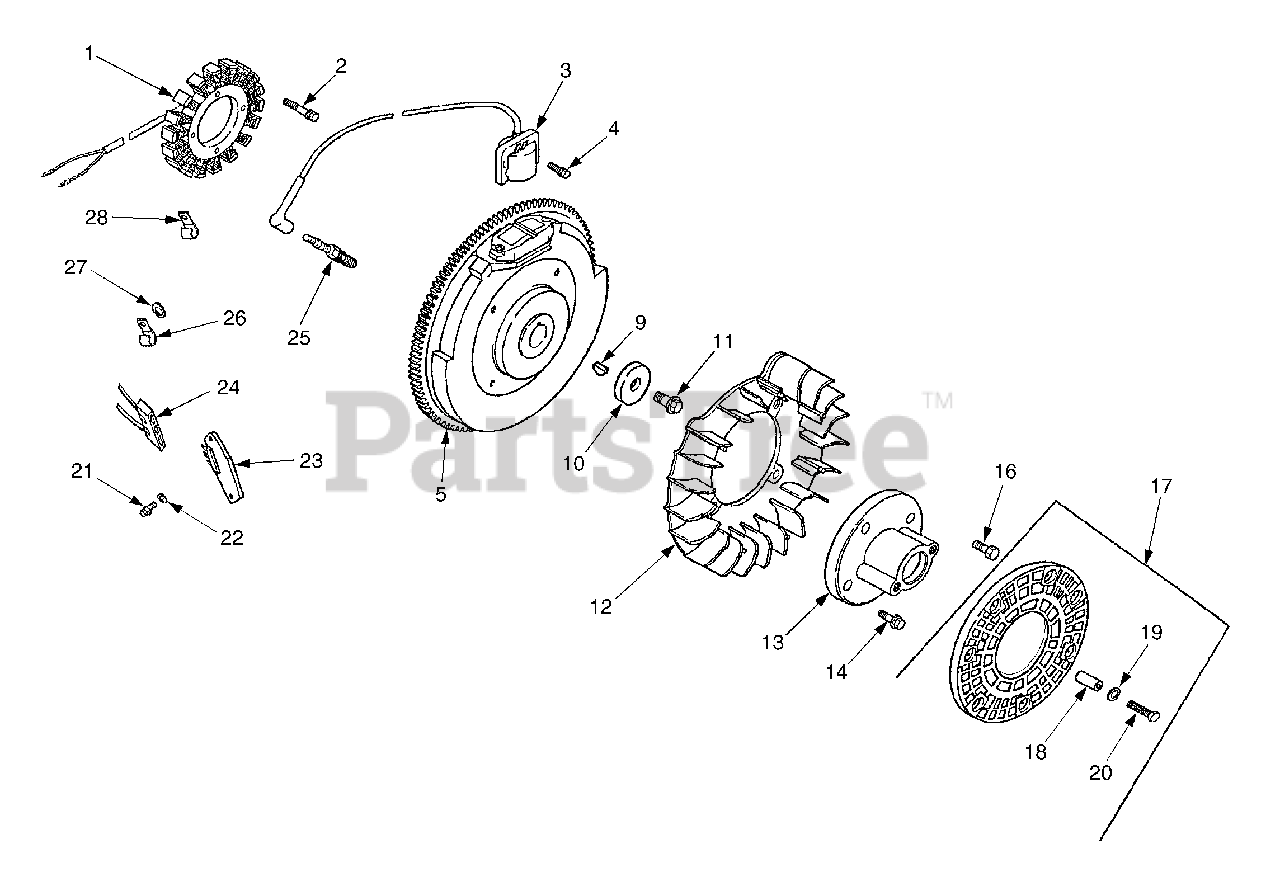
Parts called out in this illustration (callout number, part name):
1	Kit, 15 Amp Stator
2	Screw, Hex Cap M5 x 0.8 x 25
3	Module, Ignition
4	Screw, Hex Socket Hd. M5 x 0.8 x
5	Flywheel
10	Washer, Plain 3/8"
11	Screw, Hex Flange M10 x 1.5 x 46
12	Fan
13	Adapter, Drive Shaft
14	Screw, Hex Flange M10 x 1.5 x 90
16	Bolt, Shoulder, M6 x 1.0 x 16
17	Kit,Grass Screen
19	Washer, Plain 3/16"
20	Screw, Hex Cap M4 x 0.7 x 25
21	Screw, Phillips Hd. 11-16 x 7/8"
22	Washer, Plain 3/16"
23	Rectifier-regulator 15 Amp
24	Connector (3 Contact)
25	Spark Plug
26	Clip, Cable
27	Washer, Plain 1/4"
